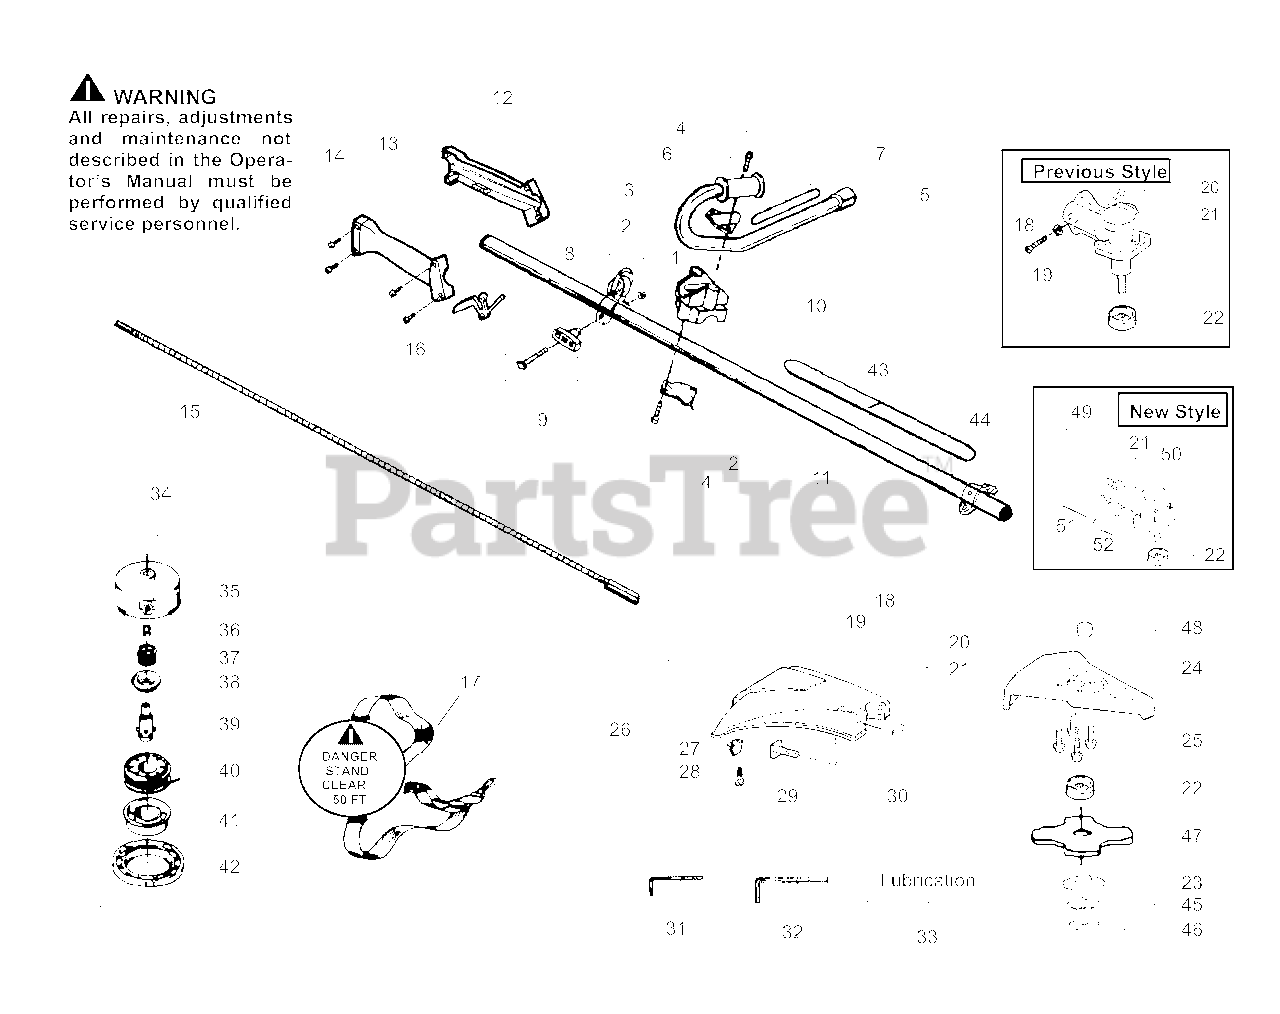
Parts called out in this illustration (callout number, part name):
2	Handlebar Bracket
3	Handlebar
5	Handlebar Cap
6	Handlebar Grip
7	Handlebar Warning Decal
8	Harness Clamp Ass'y.
9	"T" Handle Assy.
10	Handlebar Clamp
11	Drive Shaft Housing
12	Throttle Hsg. Left
13	Throttle Hsg. Right
15	Flex Drive Shaft
16	Throttle Lever
17	Shoulder Strap
18	Lockwasher
20	Screw-Pinch Clamp
21	Gear Box Ass'y.
22	Dust Cup
23	Washer
24	Metal Shield Kit
26	Shield Kit Ass'y.
27	Line Limiter
28	Screw
30	Wingnut
31	Hex Wrench (5/32)
32	Hex Wrench (3/16)
33	Shaft Lubrication
34	Cutting Head Ass'y.
36	Line Saver
38	Spring Adaptor
39	Drive Gear
40	Spool w/Line
41	Release Button
43	Decal-Warn.-Upper
44	Decal-Warn.-Lower
45	Washer-Belleville
47	4 Point Blade
48	Seal Sleeve
49	Bracket-Shield
